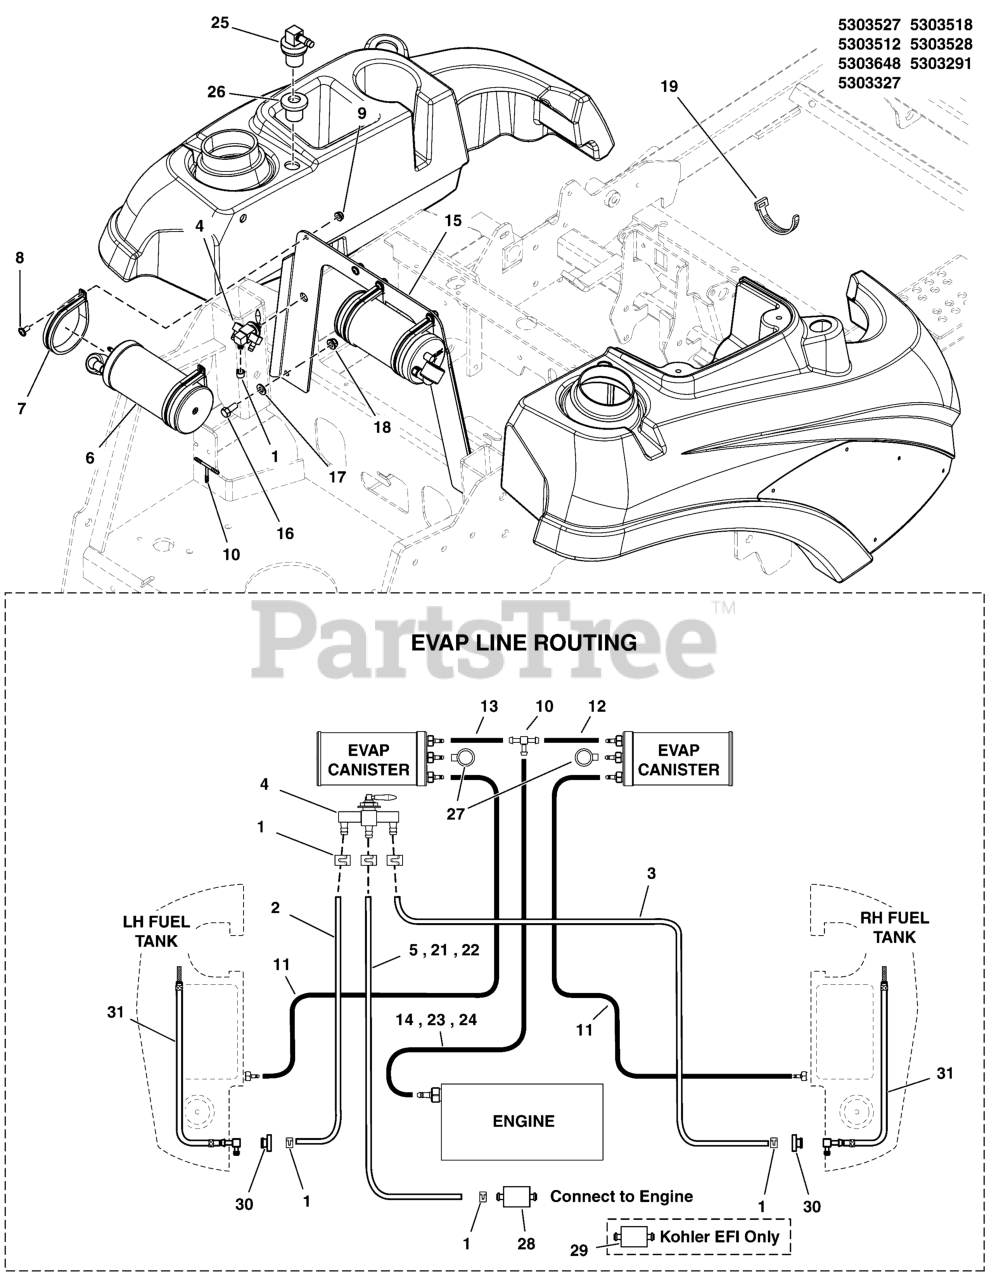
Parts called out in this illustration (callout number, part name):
1	CLAMP, HOSE, EXTERNAL, 1/2 - RED
2	HOSE, 1/4" FUEL, 9.00"
3	HOSE, 1/4" FUEL, 27.00"
4	VALVE, FUEL SHUT-OFF, 12773
5	HOSE, 1/4" FUEL, 17.50"
6	CNSTR, CARB, 6 GAL
7	CLAMP, 3" ID, CUSHIONED, STAINLESS
9	NUT, 1/4-20 HEX NYLOCK FLANGE
10	FITTING, 3/16" TEE, BARB TYPE, HDPE
11	HOSE, VAPOR, 5MM ID, 10.50 LG
12	HOSE, VAPOR, 5MM ID, 18.00 LG
13	HOSE, VAPOR, 5MM ID, 4.50 LG
14	HOSE, VAPOR, 5MM ID, 33.00 LG
15	PLATE, MOUNT, CANISTER, IS2100Z - BLK
16	BOLT, 5/16-18 X 3/4 GD5
17	WASHER, 5/16" SAE
18	NUT, 5/16-18 HEX NYLOCK FLANGE
19	NUT, 1/4-20 HEX SERR. FLANGE
20	TIE, SELF-LOCKING, 12"
21	HOSE, 1/4" FUEL, 14.00"
22	HOSE, 1/4" FUEL, 10.00"
23	HOSE, VAPOR, 5MM ID, 20.50 LG
24	HOSE, VAPOR, 5MM ID, 21.50 LG
25	REMOTE VENT ASSEMBLY
26	GROMMET (SV)
27	DUST FILTER, CANISTER (SV)
28	FUEL FILTER (SV)
29	FUEL FILTER, 29HP KOH, EFI, 25 050 42 (SV)
30	BUSHING-FUEL TANK RED RUBBER
31	HOSE ASSEMBLY (SV)
